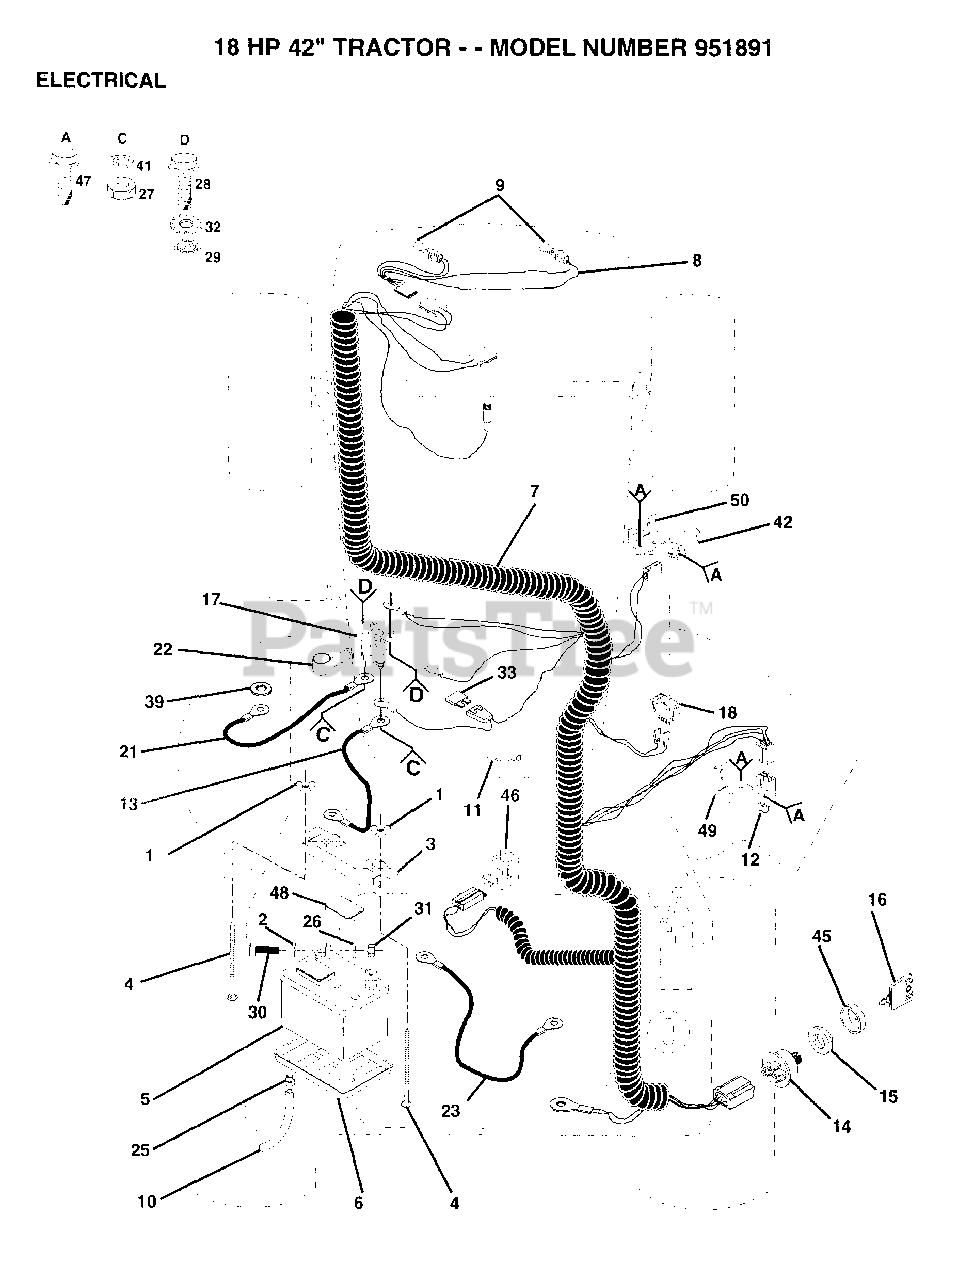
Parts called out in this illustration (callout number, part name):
2	WASHER
4	BOLT
6	"TRAY T, BATTERY"
7	HARNESS.IGN.B&S
8	"HARNESS,LIGHT SOC"
9	HEADLAMP BULB
10	"DRAIN TU T, BATT"
11	WIRE TIE
12	SWITCH INTERLOCKT
13	CABLE ASM.
15	NUT IGNITION
16	KEY
18	SWITCH LT
21	"CABLE T, BATTERY"
23	CABLE T
25	HOSE CLAMP T
26	LOCKWASHER
27	NUT
28	BOLT
29	NUT
30	BOLT LT
33	FUSE HYT
39	LOCKWASHER
42	SWITCH-INTER. GT
46	SWITCH SEAT
47	SCREW
48	"CAP,BATTERY "
49	BRACKET LT
50	SWITCH BRACKET
